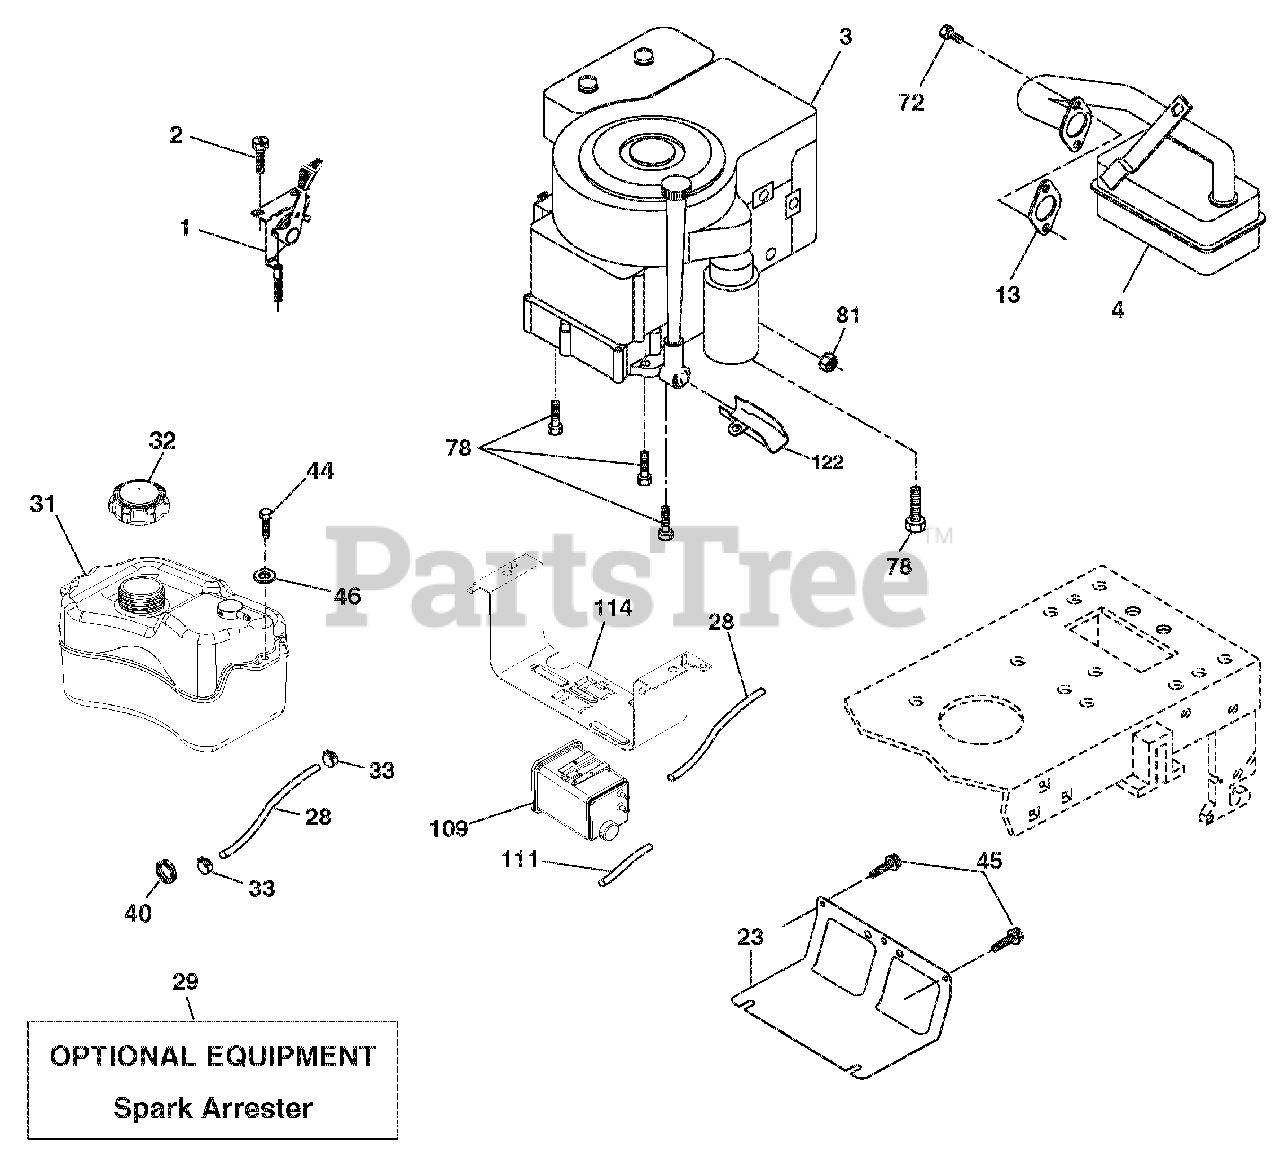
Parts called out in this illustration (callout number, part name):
1	Control Th/ch Flag
2	Screw 1/4-20 x 1/2
4	Muffler Exhaust B&S
13	Gasket Eng 1 313 Id Tin Plated
23	Shield BRN/DBR Guard
28	LINE.FUEL.22"FRONT.EMIS.CA.LP
29	KIT.SPARK ARRESTOR(392390 B&S)
31	TANK ASM.FUEL.1.50.CARB.CA.SVC
32	CAP FUEL
33	CLAMP.HOSE.BLK.
40	Bushing Snap Nyl Blk Fuel Line
44	SCREW.HEXWSH.THDROL.1/4-20X3/4
45	SCREW.HEXWSH THDR3/8-16X3/4.BL
46	WASHER.9/32 X 7/8 X 16GA.
72	SCREW.SOCKET HD.5/16-18 X .75
78	Screw 3/8-16 x <
81	Nut, Keps Hex 1/4-20 unc
109	CANISTER.CARBON.FILTER ASM.TEX
111	PURGE.LINE.CARB
114	CRADLE.CANISTER.CARBON
122	Extension Drain Oil
